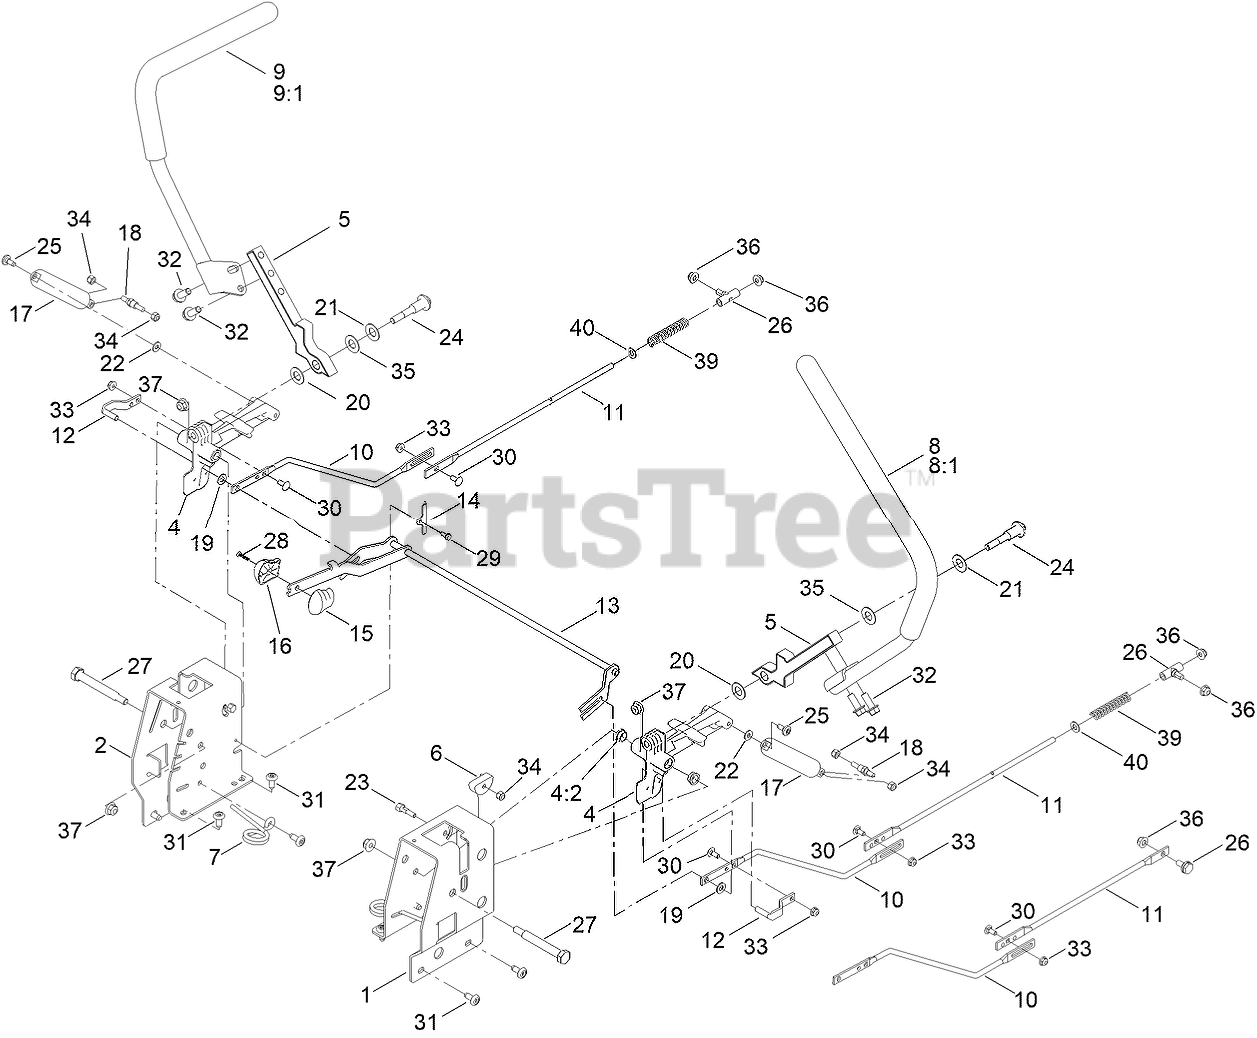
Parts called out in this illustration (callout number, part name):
1	PLATE-CONTROL BOX, LH
2	PLATE-CONTROL BOX, RH
4	ACTUATOR ARM ASM
4:2	BUSHING-FLANGE
5	ARM-CONTROL
6	ECCENTRIC
7	SPRING-TORSION
8	HANDLE-CONTROL, LH
9	HANDLE-CONTROL, RH
10	ROD-HYDRO, FRONT
11	ROD-HYDRO, REAR
12	PIN-ROD, HYDRO
13	SPEED CONTROL ASM
14	PLATE-RETAINER
15	KNOB-RH
16	KNOB-LH
17	DAMPER-NON CAVITATING
18	STUD-DAMPER
19	SPACER-NYLON
20	WASHER-NYLON
21	WASHER-BELLEVILLE
22	WASHER
23	BOLT-PIVOT, ECCENTRIC
24	BOLT-PIVOT
25	SCREW-SHOULDER
26	MOUNT-ROD, HYDRO
27	BOLT-PIVOT
28	SCREW-PPH
29	SCREW-TAPTITE
30	SCREW-CARR
32	SCREW-HHF
33	NUT-HF
34	NUT-LOCK, NI
35	WASHER
36	NUT-HF
37	NUT-HF, NI
39	SPRING-COMPRESSION
40	WASHER-PLAIN
